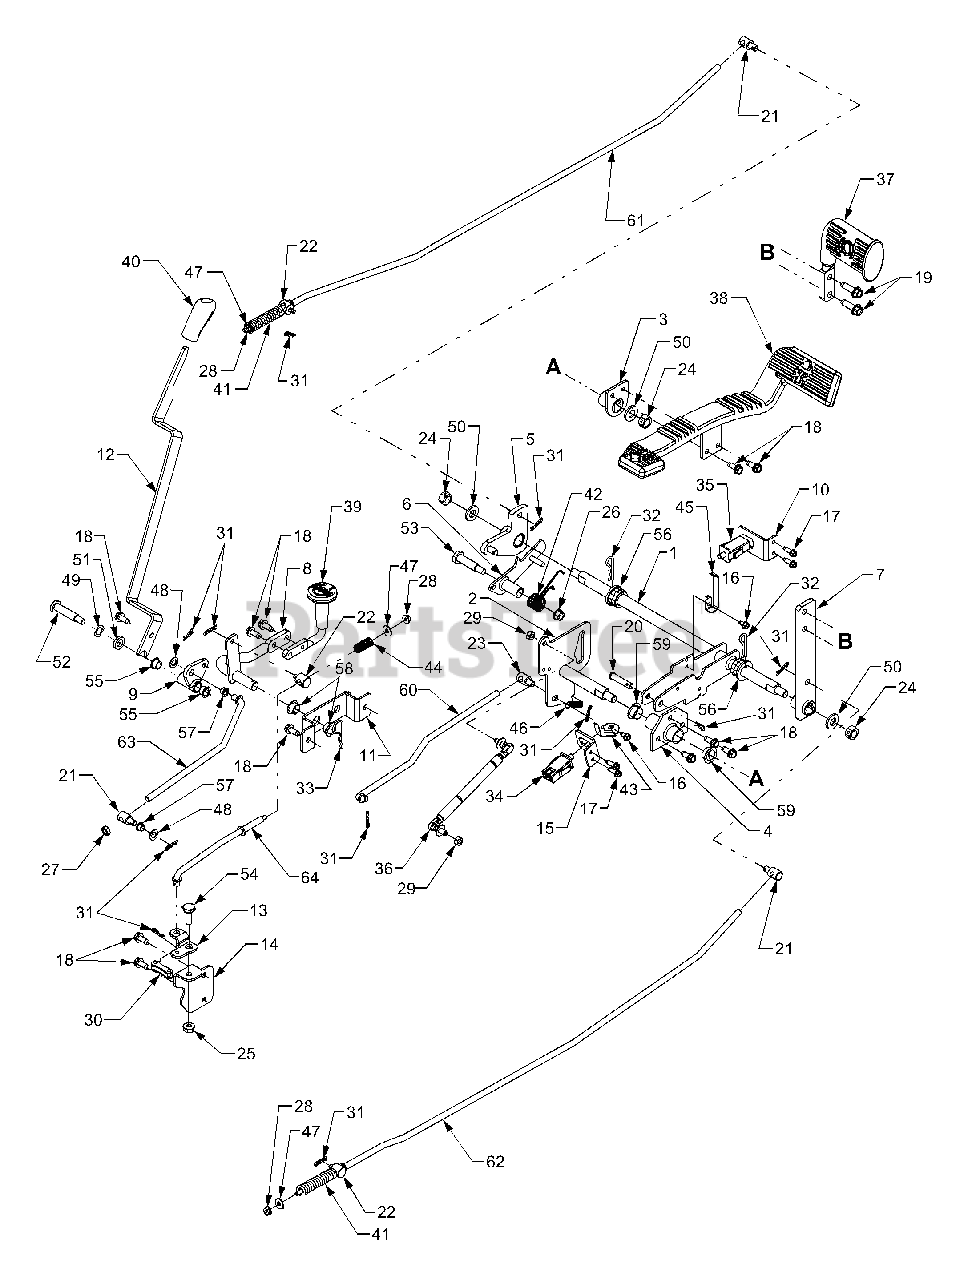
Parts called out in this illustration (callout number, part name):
1	Shaft Assembly, Brake
2	Shaft Assembly, Forward
3	Link Assembly, Pedal
4	Plate, Bearing
5	Link Assembly, Brake LH
6	Link Assembly, Parking Brake
7	Link Assembly, Brake RH
8	Shaft Assembly, Differential
9	Link, PTO Select
11	Bracket, Differential Pivot
12	Handle, PTO
13	Link, Differential Pivot
14	Bracket, Diff. Actuator Mtg.
17	Screw, Hex Wash Hd Tapp 1/4-20 x .75
18	Screw, Hex Wash Hd Tapp 5/16-18 x .75
19	Screw, Hex Wash Hd Tapp 3/8-16 x 1.0
20	Pin, Clevis, 3/8 x 1.75
21	Ferrule, 3/8-24 x .375 Dia. Hdn
22	Ferrule, Brake
23	Ferrule, 3/8-24 x .37
24	Nut, Hex Lock, 1/2-20
25	Nut, Hex Flange Lock, 3/8-24
26	Nut, Hex Flange Lock, 3/8-16
27	Nut, Hex Jam, 3/8-24
28	Nut, Hex Flange Lock, 1/4-20
29	Nut, Hex, M8 x 1.25 GR8.8
30	Link, Chain
31	Pin, Internal Cotter
32	Pin, Internal Cotter
33	Pin, Internal Cotter
34	Switch, Plunger
35	Switch, Plunger
36	Cylinder, Damper
37	Pedal, Brake
38	Pedal, Forward/Reverse
39	Pedal, Differential
40	Grip, Handle
41	Spring, Compression
42	Spring, Torsion
43	Spring, Rev/No Cut
44	Spring, Compression
45	Spring, Switch Actuator
46	Spring, Extension
47	Washer, Flat, .28 x .74 x .063
48	Washer, Flat, .375 x .738 x .063
49	Washer, Wave, .53 x .78 x .013
50	Washer, Flat, .53 x .1.06 x .134
51	Washer, Flat, .53 x .875 x .15
52	Screw, Shoulder, .50 x 1.825
53	Screw, Shoulder, .498 x 1.635
54	Screw, Shoulder, 1/2 x .180: 3/8-24
55	Bearing, Nylon. .50 ID x .341
56	Bearing, Hex Flange, .752 ID
57	Bearing, Flange, .375 x .58 x .25
58	Bearing, Flange, .626 x .938 x .344
59	Bearing, Flange, .751 x 1.125 x .375
60	Rod, Hydro Control
61	Rod, Brake, LH
62	Rod, Brake, RH
63	Rod, PTO Control
64	Rod, Diff. Lock Control
